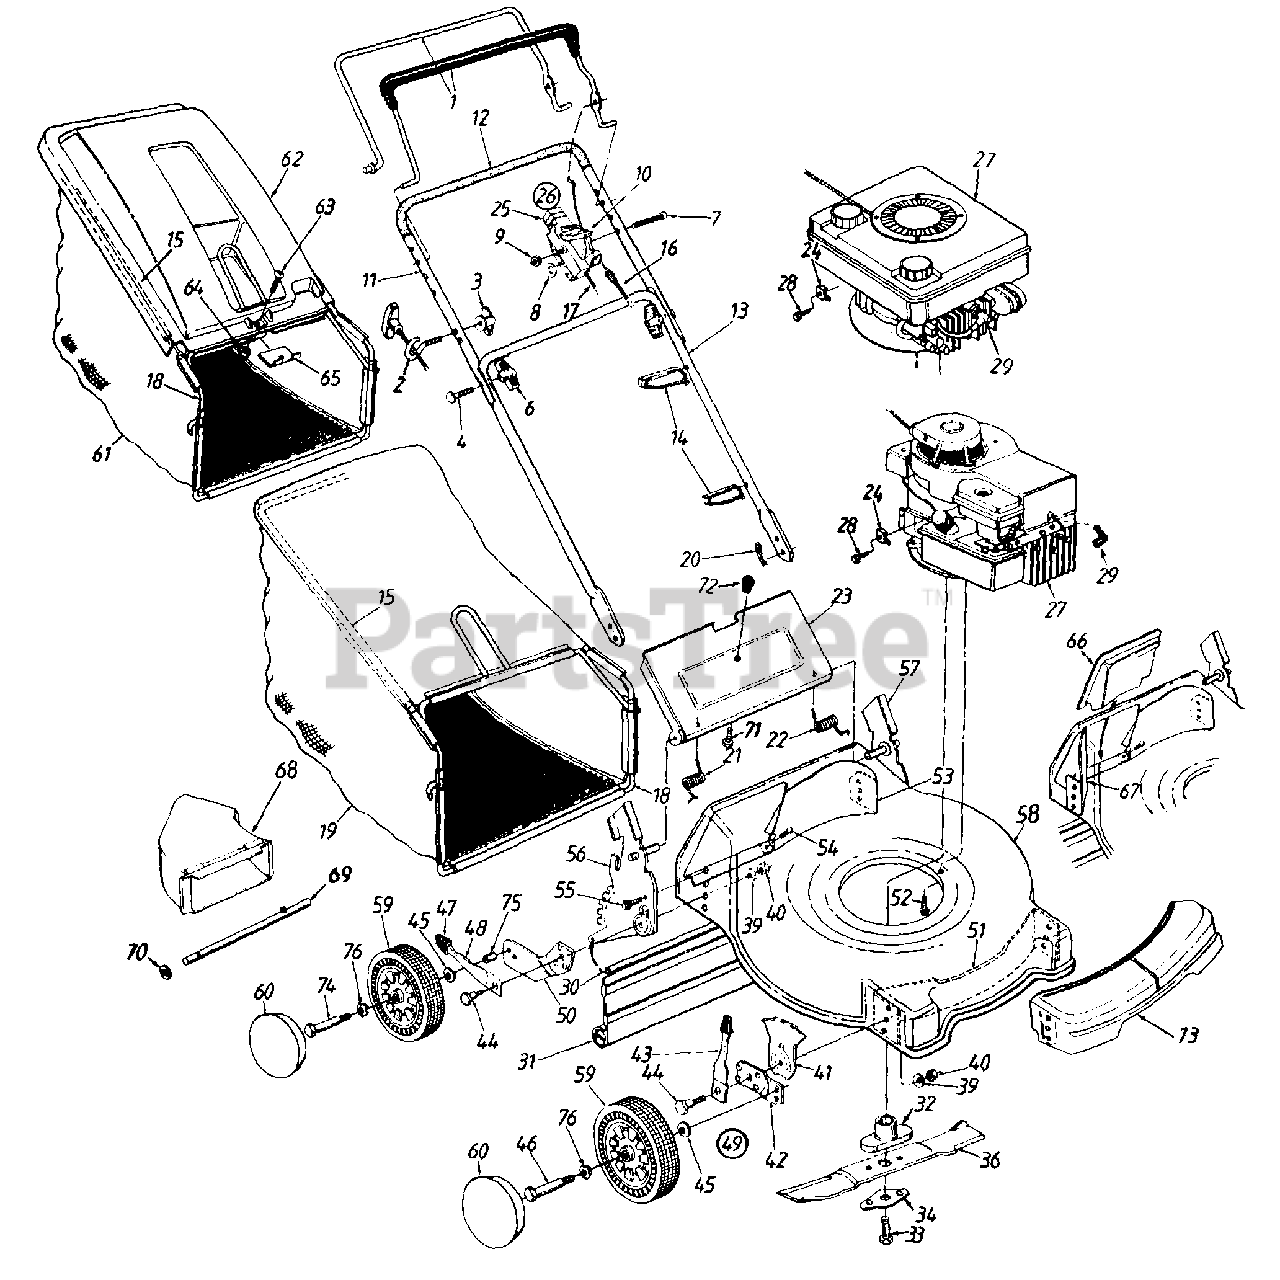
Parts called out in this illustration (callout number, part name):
2	Rope Guide
3	Handle Knob 1/4-20 Thd.
4	Curved Hd. Bolt 5/16-18 x 2" Lg
6	Hand Knob
7	Oval C-Sunk Mach. Scr.
8	Spring Washer .66" I.D.
9	Hex L-Nut 1/4-20 Thd.
10	Throttle Lever
14	Cable Tie
16	Control Cable-39"
17	Throttle Control Wire - 55"
20	Int. Cotter Pin 5/16" Dia.
21	Door Spring - R.H.
22	Door Spring - L.H.
25	Throttle Body
26	Throttle Box Comp.
27	Engine
28	Hex Wash. Hd. Scr. #10-32 x .62" Lg. (B & S)
29	Spark Plug Boot
30	Wire Rod
31	Rear Flap
32	Blade Adapter Kit
33	Hex Bolt 3/8-24 x 1.5" Lg.
34	Blade Bell Support
36	21" Mulching Blade
39	Bell-Wash. .39" I.D. x 1.38"
40	Hex Nut 3/8-16 Thd.
41	Height Adj. Plate
43	Spring Lever Ass'y. w/Knob
44	Shld. Bolt .5" Dia. x .357"
45	Bell-Wash. .38" I.D. x.88" O.D.
46	Axle Bolt
47	Spring Lever Knob
48	Spring Lever
49	Height Adj. Assembly Comp. - R.H.
50	Pivot Bar R.H.
54	Torx Mach. AB-Tap Scr. 1/4 x 62"
55	Wash. Scr. 1/4 -14 x .625
56	Handle Bracket Assembly - R.H.
57	Handle Bracket Assembly - L.H.
60	Hub Cap - Gray, Rad. Spoke
61	Grass Bag
62	Hard Top Cover
63	Pan Hd. Mach. Scr. 1/4-20 x .5" Lg.
64	Hex Nylon L-Nut 1/4-20 Thd.
66	Mulching Baffle Plug
68	Deflector
69	Rod
70	Push Speed Nut
71	Truss Scr. #10-24 x .38" Lg.
73	Deck: Front Cover
74	Rear Axle Bolt
75	Spacer
76	Wave Washer
